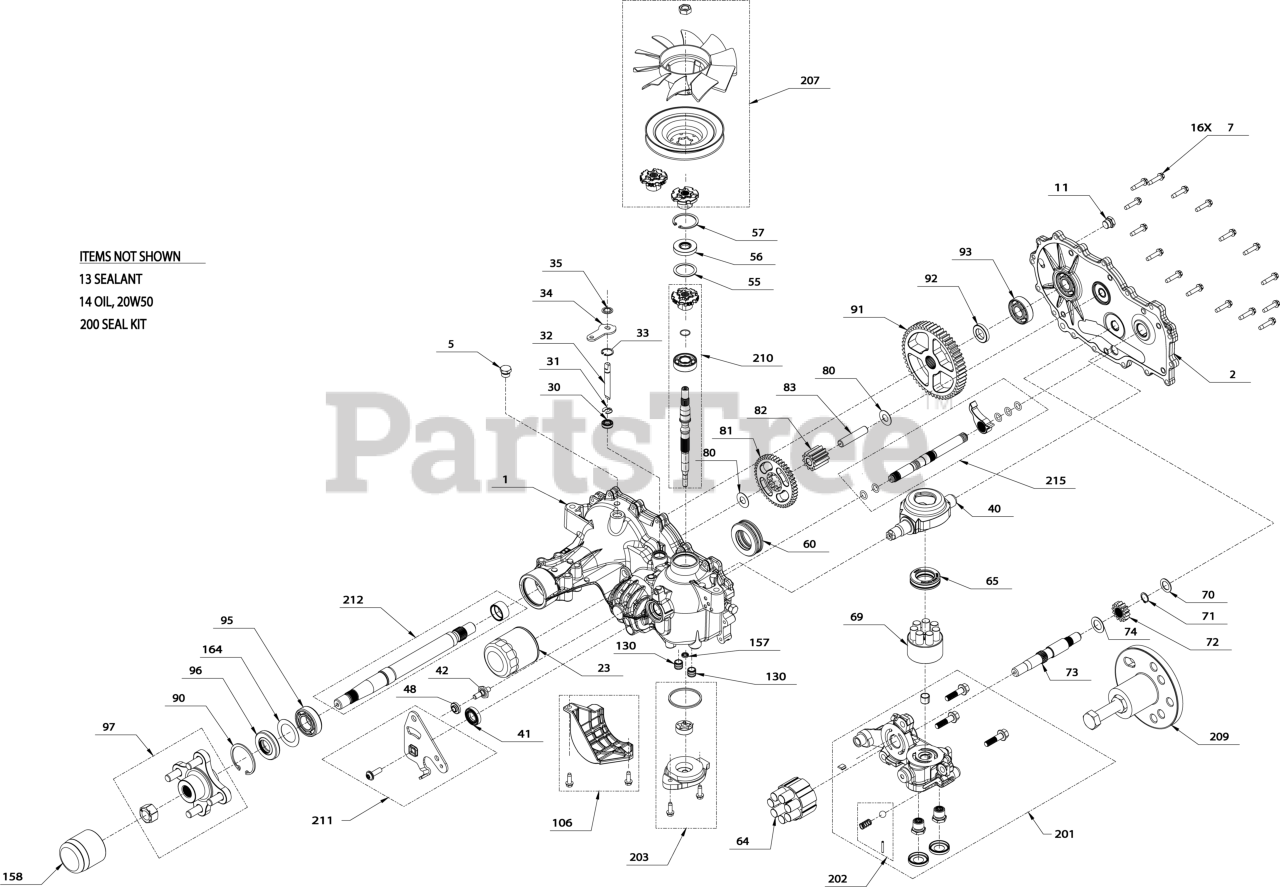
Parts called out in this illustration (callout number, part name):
1	KIT, MAIN HOUSING RH, CHARGE, CONTROL
2	KIT, COVER SIDE RH
5	PLUG EXT HEX VENT 9/16 18
7	SCREW,HEX WASHER 1/4-20X1.125
11	PLUG EXT HEX VENT 9/16 18
13	SEALANT TUBE 10.1OZ.
14	FLUID, HYDRO 15W50 QT
14	FLUID, HYDRO 20W50 QT
23	FILTER, HYDRO-GEAR 2800 TRANS
30	Seal, lip .375 x 375 x 325
31	RING. RETAINING
32	ROD, BYPASS
33	RING, RET .750
34	ARM, BYPASS
35	RING, RTNG .
40	TRUNNION, SWASHPLATE
41	SEAL, LIP 18X32X7
42	STUD. SHORT 5/16-24
48	SPACER
55	WASHER 1.23X1.56X.04
56	SEAL, LIP 17 X 40 X 7 HNBR
57	RING, RET 1.56 INT
60	HG THRUST BEARING (51462)
64	HG 16CC CYLINDER BLOCK (71579)
65	BEARING. THRUST 30 X 52 X 13
69	ASSY, BLOCK 7 PISTON
70	WASHER .63X1.0X.05
71	RING, RET 62 EXT
73	SHAFT, MOTOR
74	WASHER .71 X 1.16 X .04
80	WASHER .5X1.0X.032
81	GEAR 45 TOOTH
83	JACK SHAFT (PIN)
90	RING, RETAINING
91	GEAR 54 TOOTH
92	SPACER
93	KIT, BEARING
95	BEARING, BALL 25.4 X 52 X 15
96	SEAL, LIP
97	KIT, HUB 4 BOLT
106	KIT FILTER GUARD
130	TUBE CHARGE TRIPLE ORING
157	KIT GEROTOR SEAL
158	CAP, AXLE
164	WASHER, 1.355 x 2.035 x .021 FLAT
200	KIT, SEAL (ZT-2800)
201	KIT, CENTER SECTION, RH CHARGE
202	KIT CHARGE RELIEF
203	KIT, CHARGE
207	KIT, FAN / PULLEY
209	HUB PULLER 5 BLT
210	KIT INPUT SHAFT
211	KIT, ARM, CONTROL
212	KIT SHAFT AXLE
215	KIT OUTBOARD RH
